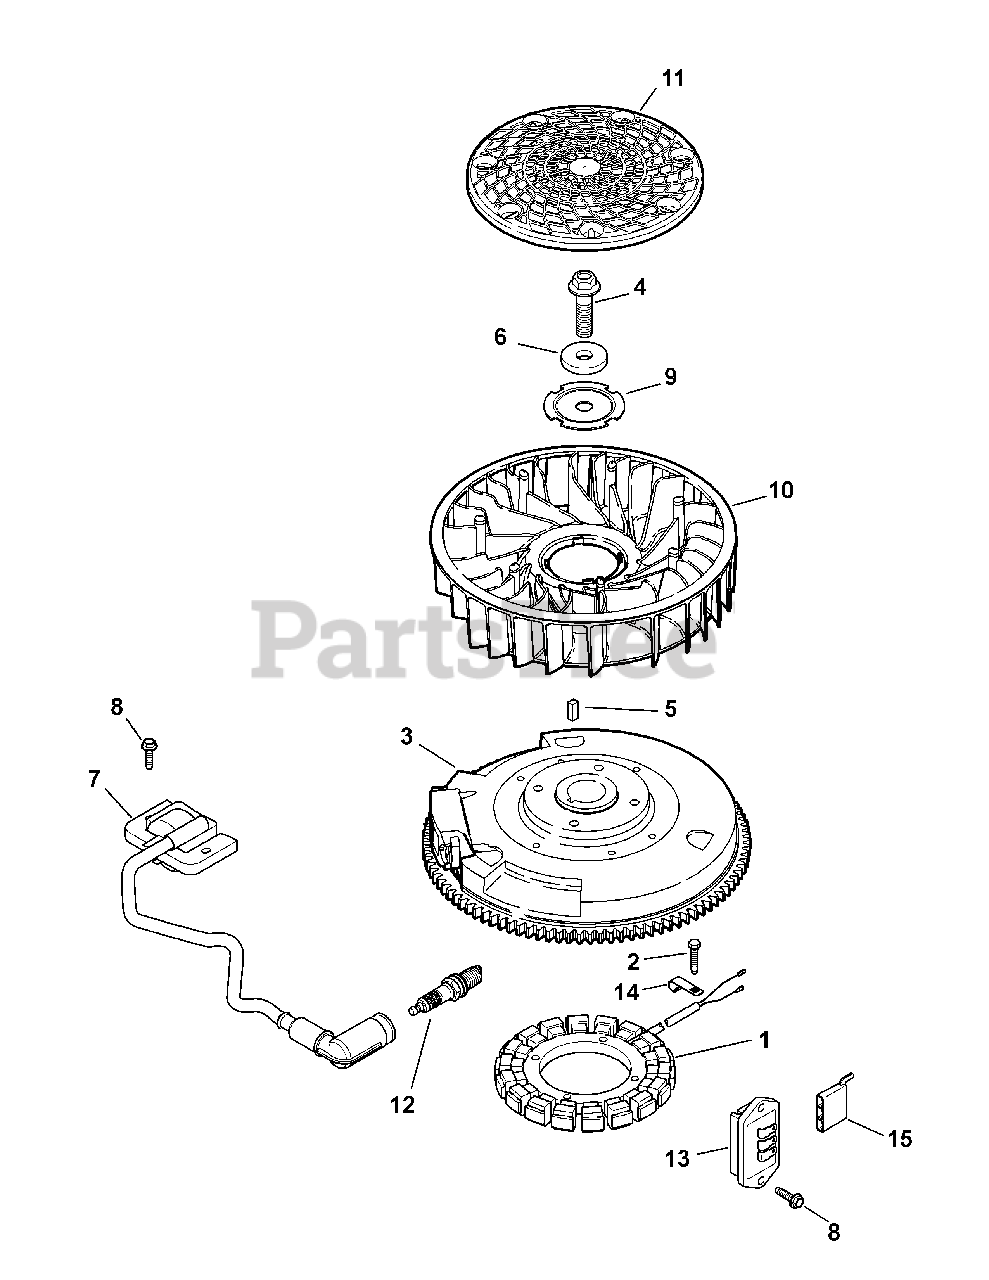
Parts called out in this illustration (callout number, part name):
1	15 Amp Stator Kit
2	Thd. Frm. Screw, M5 X 0.8 X 25
4	Screw, Hex Flange
7	Ignition Module
8	Flg. Thd. Frm. Screw, M5 X .8 X 20
9	Fan Mounting Plate
12	Spark Plug
13	Regulator/Rectifier
